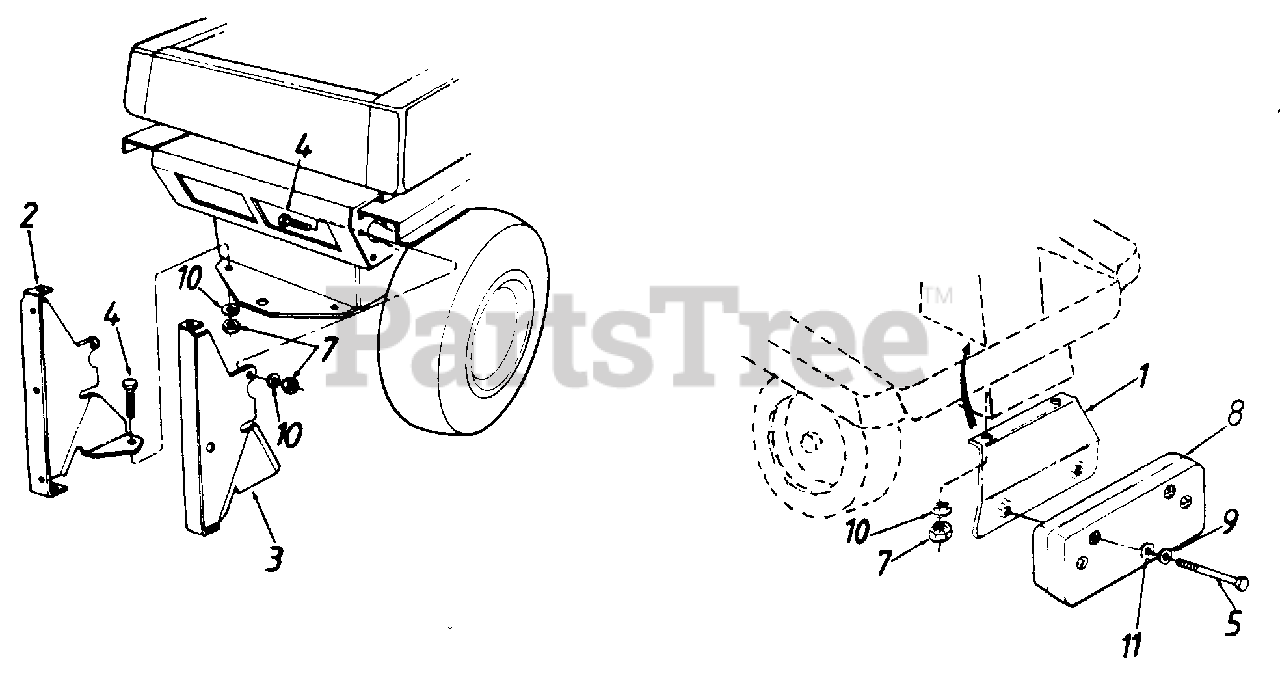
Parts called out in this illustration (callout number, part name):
1	Counterweight Support Brkt. 1
2	Catcher Support Brkt.-R.H. 1
3	Catcher Support Brkt.-L.H. 1
4	Hex Bolt 5/16-18 x 1.0" Lg. 4
5	Hex Bolt 3/8-16 x 4.5" Lg. 2
7	Hex Nut 5/16-18 Thd. 6
8	Front Counterweight
9	Bell-Wash. 3/8" I.D. 2
10	L-Wash. 5/16" I.D. 6
11	Fl-Wash. .390" I.D. x 1.12" O.D. 2
